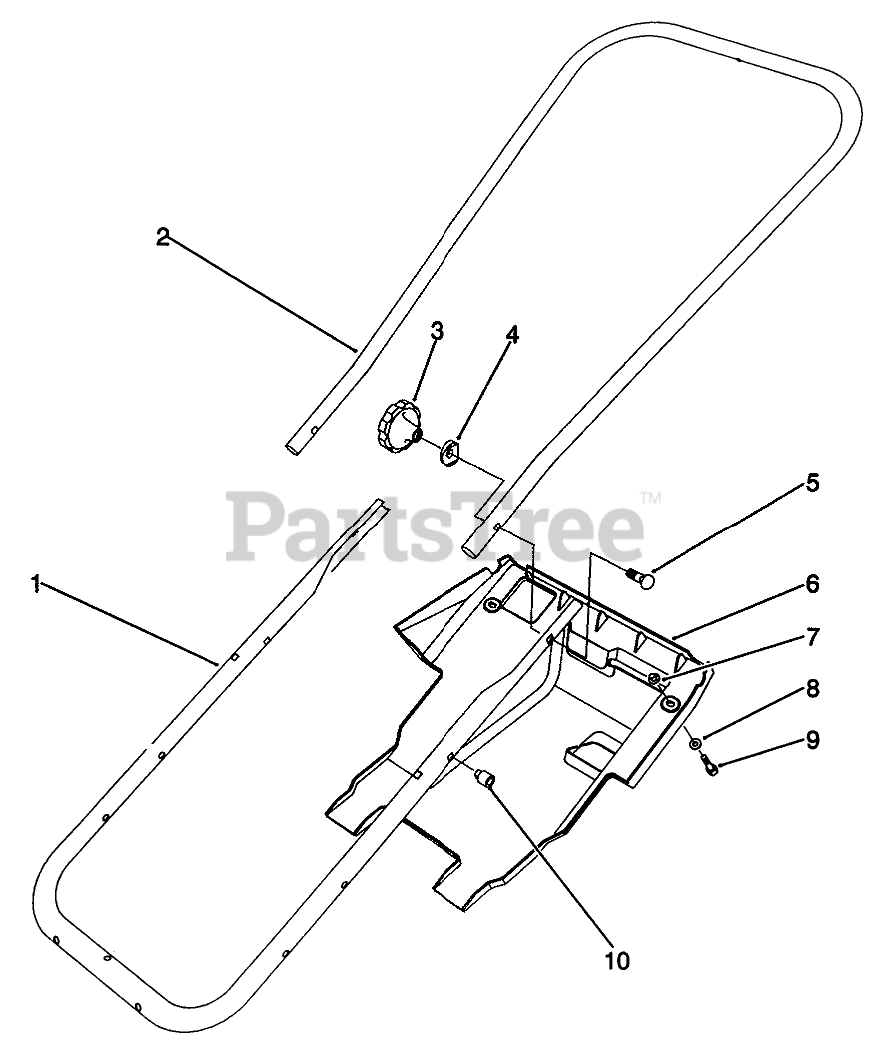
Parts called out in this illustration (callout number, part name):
1	Tube-Frame
2	Handle-Upper
4	WASHER-CURVED
5	SCREW-HANDLE
6	SHROUD
7	Nut-Push
8	WASHER-FLAT
9	SCREW-HWHTF
10	NUT-EXPANSION
